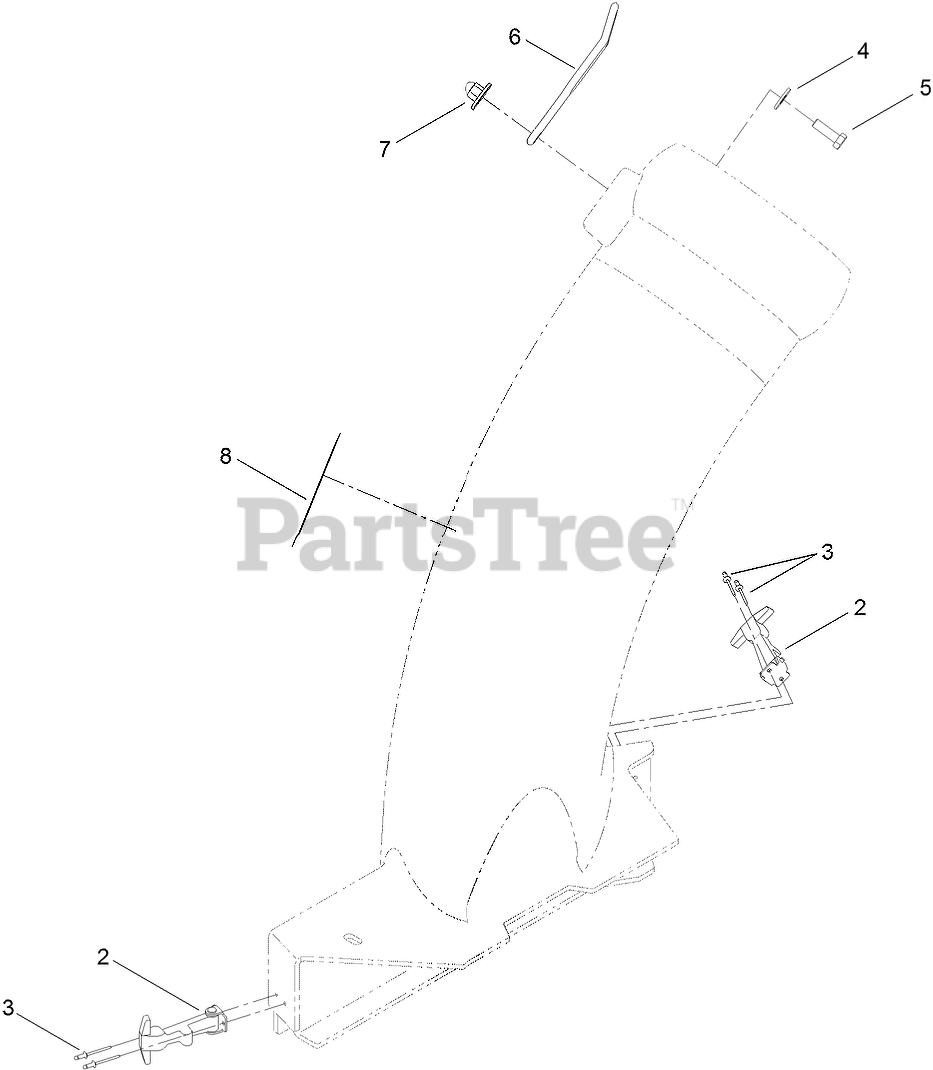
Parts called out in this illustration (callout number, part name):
2	HANDLE ASM
3	RIVET-POP
4	WASHER-FLAT
5	SCREW-HH
6	RETAINER-DUCT
7	NUT-IMPELLER
8	DECAL-DANGER
